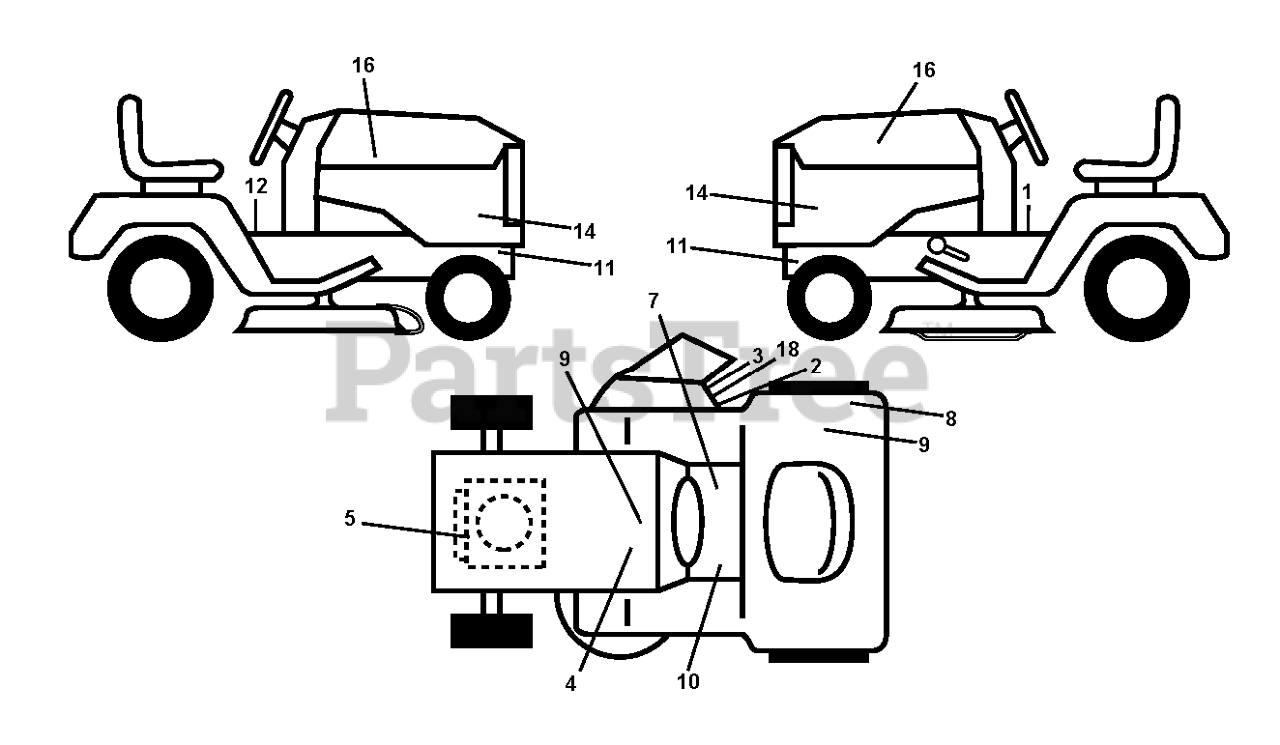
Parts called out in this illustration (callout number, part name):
1	DECAL
2	DECAL.MOWER.SCH.48/54
3	DECAL.INTERNATIONL.CUTFINGER
4	DECAL BTRY SYMBOLS
5	DECAL
7	LABEL
8	DECAL
9	DECAL 80 DBA
10	DECAL
12	DECAL PARK BRAKE
16	DECAL.HOOD.LOGO.ORANGE.HUSQVAR
18	DECAL, DEFLECT WARNING
